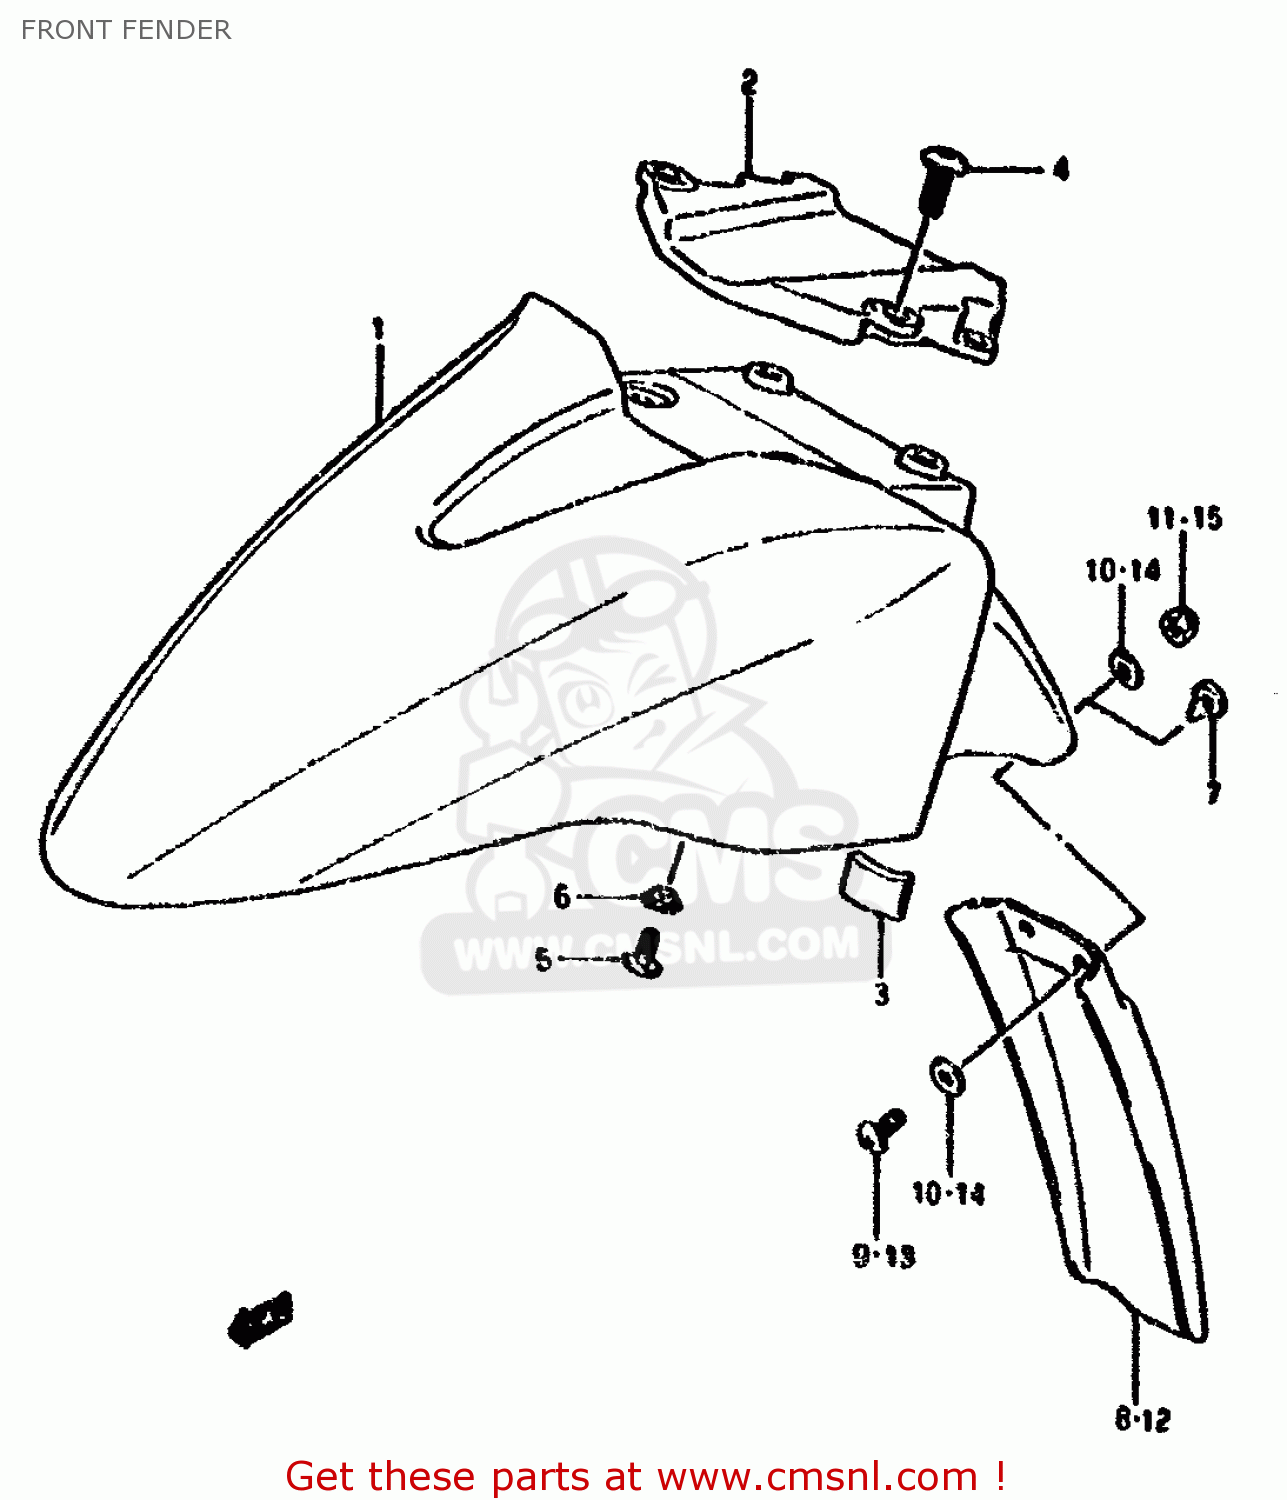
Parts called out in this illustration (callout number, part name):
1	FENDER,FRONT
2	BRACE,FR FENDER
3	CUSHION,FR FENDER
4	SCREW(8X16)
5	SCREW
6	WASHER
7	PLUG(OD:10)
8	GUARD,FR FENDER MUD
9	SCREW 5X10
10	WASHER,5MM
11	NUT
12	GUARD,FR FENDER MUD
13	SCREW 5X10
14	WASHER,5MM
15	NUT
